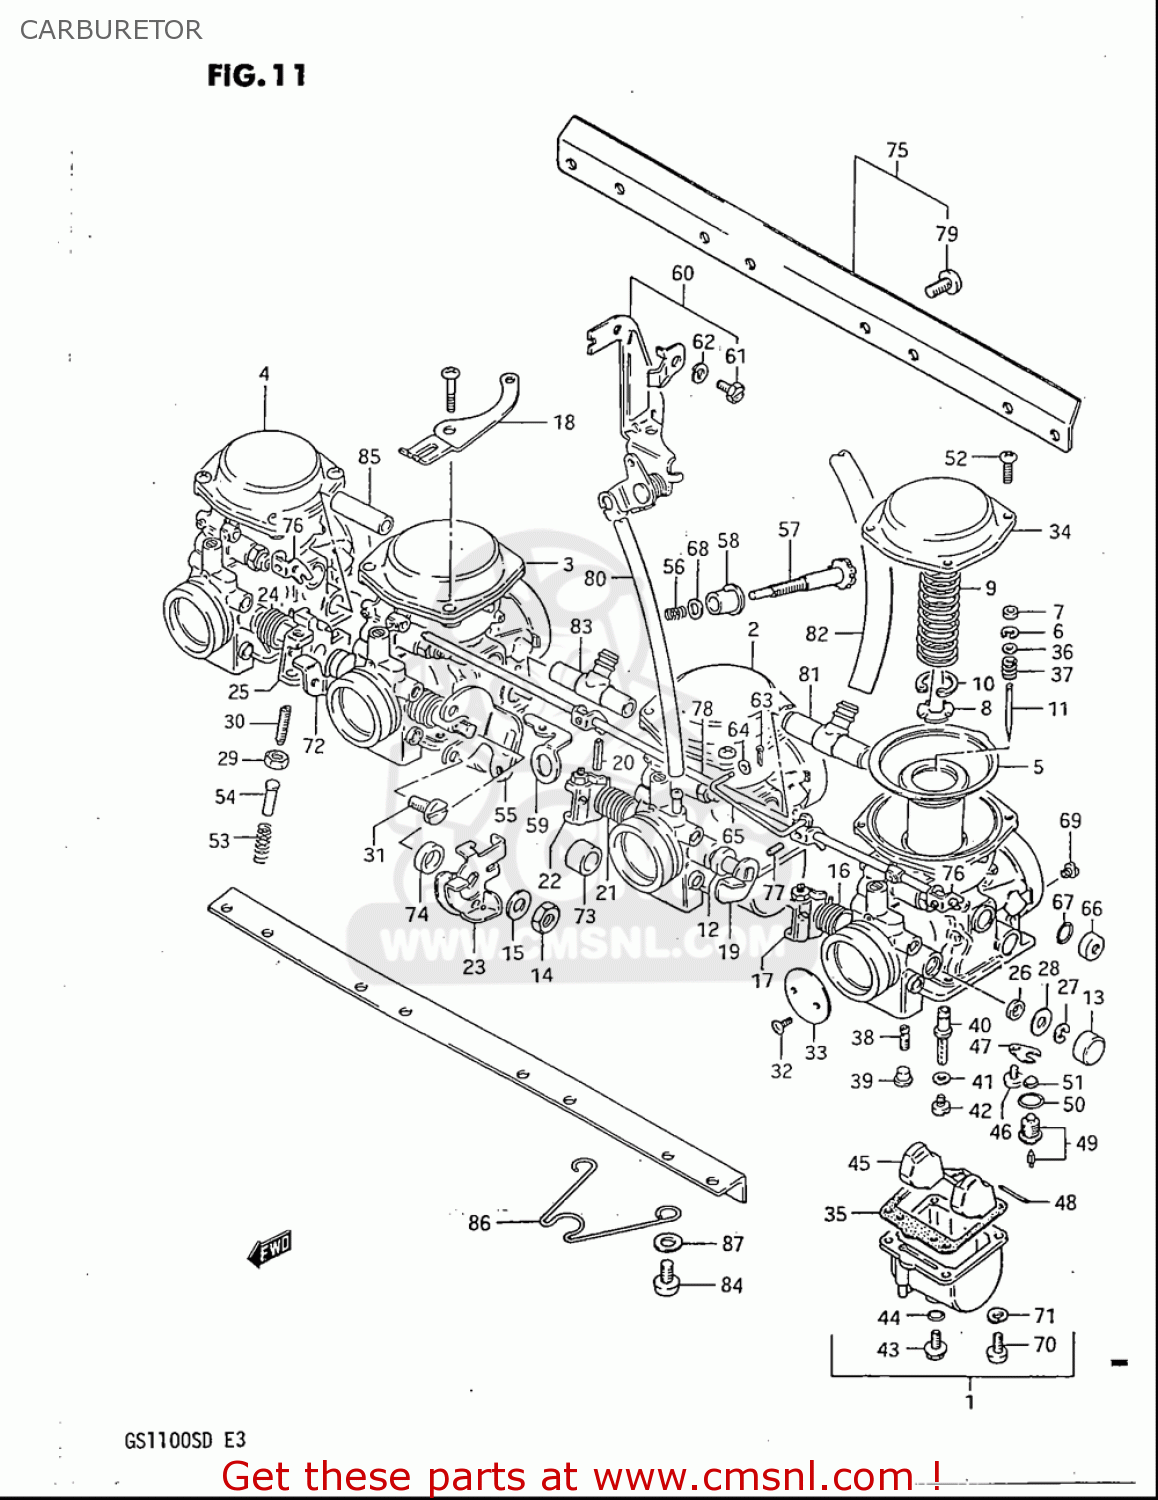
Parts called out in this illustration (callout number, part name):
5	DIAPHRAGM,CARBURETOR
6	CLIP,NEEDLE
7	RING
8	HOLDER,GUIDE
9	SPRING
10	E RING
11	NEEDLE,JET
12	GASKET
13	CAP
14	NUT
20	PIN,THROTTLE SHAFT
23	LEVER ASSEMBLY,THROTTLE
26	SEAL
27	E RING
28	GASKET,THROTTLE SHAFT (NAS)
29	NUT
30	SCREW
31	SCREW
32	SCREW
34	COVER,DIAPHRAGM
35	GASKET,FLOAT CHAMBER (NAS)
36	WASHER
37	SPRING
38	JET,PILOT(45)
39	PLUG,NEEDLE JET
41	WASHER
42	JET,MAIN(112.5)
43	PLUG,DRAIN
44	GASKET (NAS)
45	FLOAT
46	SCREW 4X6
47	PLATE,NEEDLE VALVE FITING
48	PIN,FLOAT
49	VALVE ASSY,NEEDLE
50	O RING,NEEDLE VALVE SEAT
51	FILTER
52	SCREW
53	SPRING,THROTTLE SCREW
54	PIN,THROTTLE LEVER
56	SPRING
57	SCREW
58	BUSH
60	BRACKET ASSY
61	BOLT
62	WASHER,LOCK
64	SEAT,SPRING
65	LEVER ASSY
66	CAP,STARTER VALVE
67	O RING
68	WASHER
70	SCREW
71	LOCK,WASHER
74	RING
76	LEVER
77	SCREW
78	SHAFT,STARTER
79	SCREW
80	HOSE(4.5X8.5X600)
81	NIPPLE
82	HOSE(6.5X11.5X600)
83	NIPPLE
84	SCREW
85	NIPPLE
86	CLIP
87	WASHER
